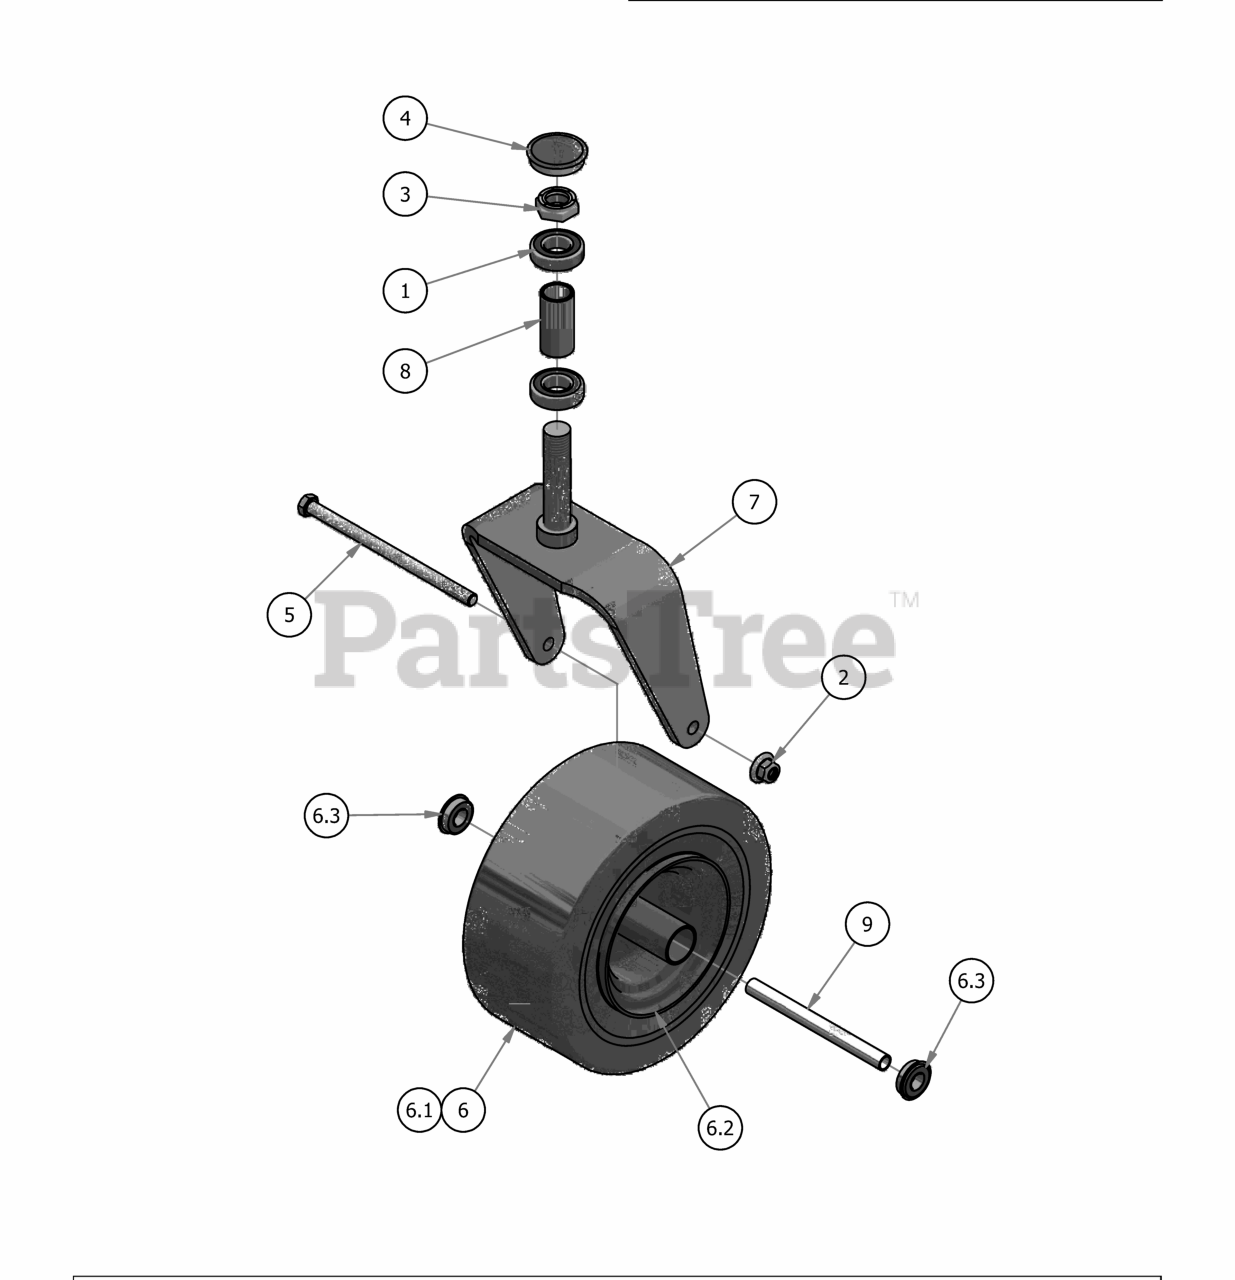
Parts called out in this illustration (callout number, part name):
1	Caster Bearing 2016 - 1641 Bearing
2	1/2-13 Nylon Flange Nut
3	1" Fine Thread 1/2 Nylock Nut
4	2017 Bearing Cover
5	1/2" x 9" GR 5 Hex Bolt
6	Tire and Wheel Assembly
6.1	13 x 6.50 - 6 Tire
6.2	Front Tire Rim
6.3	BEARING WITH RETAINER
7	Front Fork
8	2016 Front Bearing Spacer
9	Front Wheel Spanner
